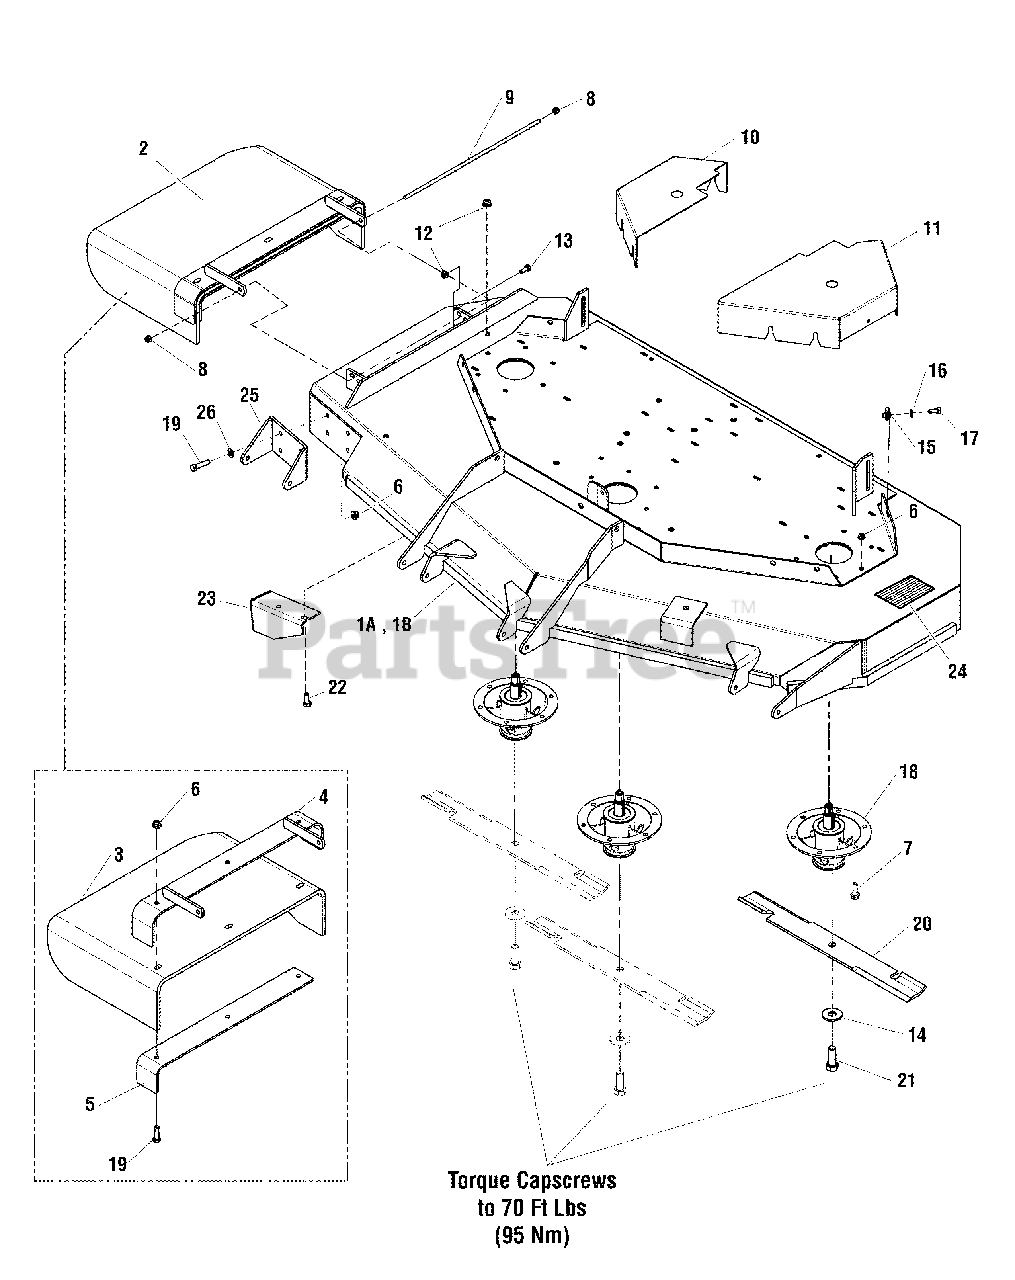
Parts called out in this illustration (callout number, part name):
1A	DECK SHELL W/DECALS, 61" SIDE DISCHARGE
1B	DECK SHELL W/DECALS, 61" SIDE DISCHARGE
2	PURCHASE INDIVIDUAL REPLACEMENT PARTS
3	CHUTE, DISCHARGE, BEND RUBBER (SV)
4	WELD, FRAME CHUTE, 61 - BLK
5	SUPPORT, DISCHARGE CHUTE, 61/72 - BLK
6	NUT, 3/8-16 HEX NYLOCK FLANGE
7	BOLT, 5/16-18 X 1" FLANGE
8	NUT, 5/16-24 HEX NYLON LOCK
9	ROD MOUNT, CHUTE 61"
10	GUARD, 61", RH - ORANGE
11	GUARD, 61" - LH - ORANGE
12	NUT, 5/16-18 HEX NYLOCK FLANGE
13	SCREW-HEX WZ LOCK FLNG 5/16-18X0.750BLK
14	WASHER, 5/8" GRADE 8, YZ
15	BODY CLIP, 5/16-18 X 1/2" DEEP
16	WASHER, 5/16" GD.9 FLAT
17	BOLT, 5/16-18 X 3/4 GD5
18	ASSM, SPINDLE, CAST IRON
19	BOLT, 3/8-16 X 1 1/2"
20	BLADE, 21 X .25 X 2.5, 1 X 3.5 (SET OF 3)
21	BOLT, 5/8-11 X 1-3/4" GD8
22	BOLT, 5/16-18 X 3/4, CARRIAGE
23	PLATE, DEFLECTOR - BLK
24	SAFETY WALK, 9.75 X 6.00
25	PLATE, BRACKET, ANTI SCALP - ORANGE
26	WASHER, 3/8 SAE
